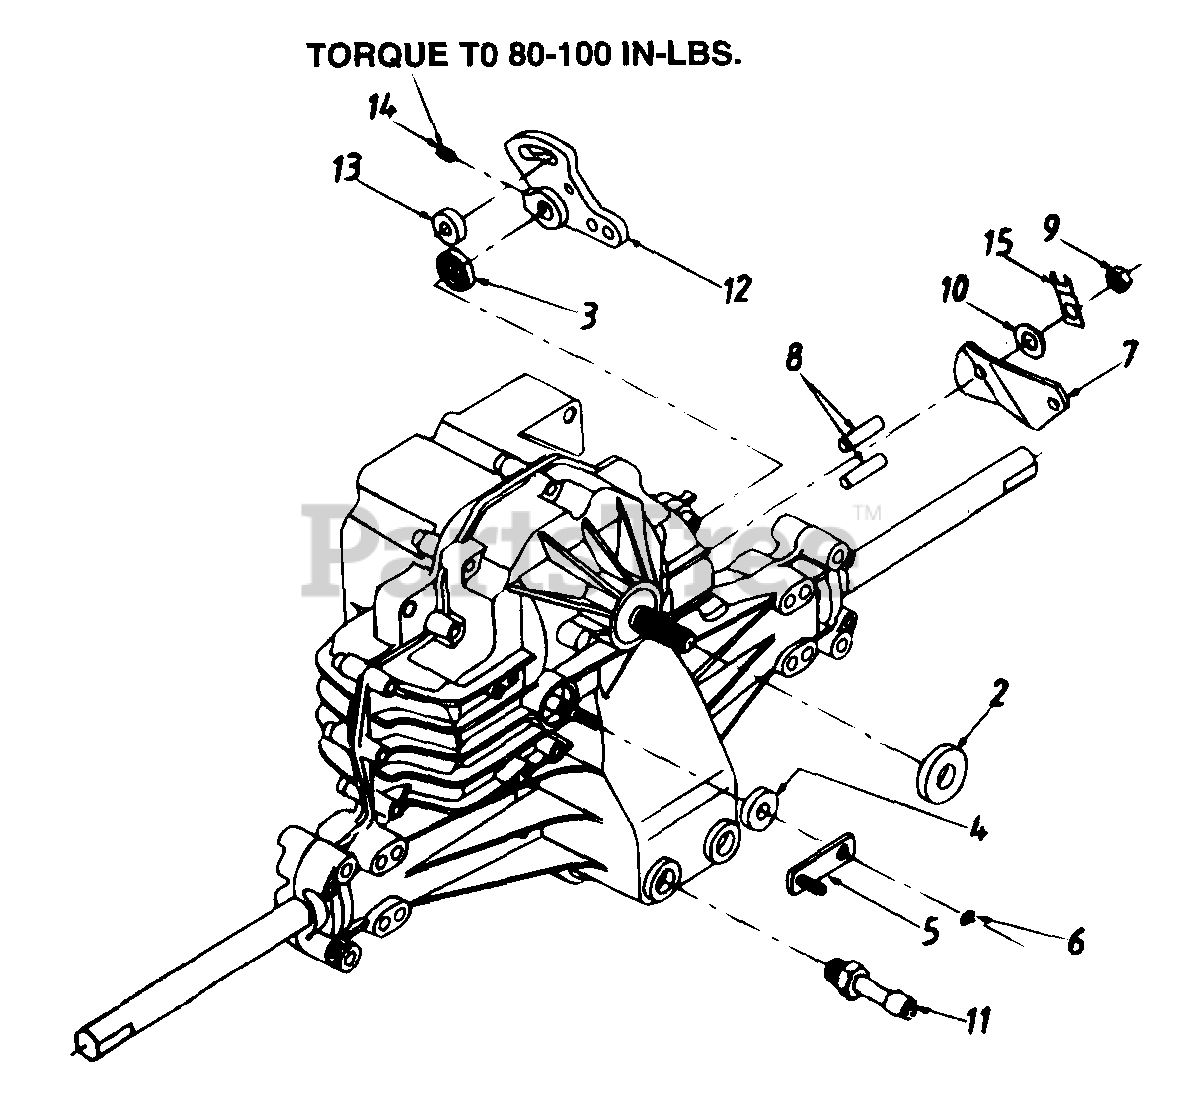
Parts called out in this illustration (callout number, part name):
4	Seal - Lip 10X25X7
5	Arm - Bypass
6	Ring - Retaining
7	Arm - Actuating
8	Pin - Actuating
9	Nut - Hex Lock 5/16-24 UNJC
10	Washer 7/16" x 7/8" x .06"
11	Breather Ass'y.
12	Arm - Control
13	Puck - Dampener
15	Strap, Locking
